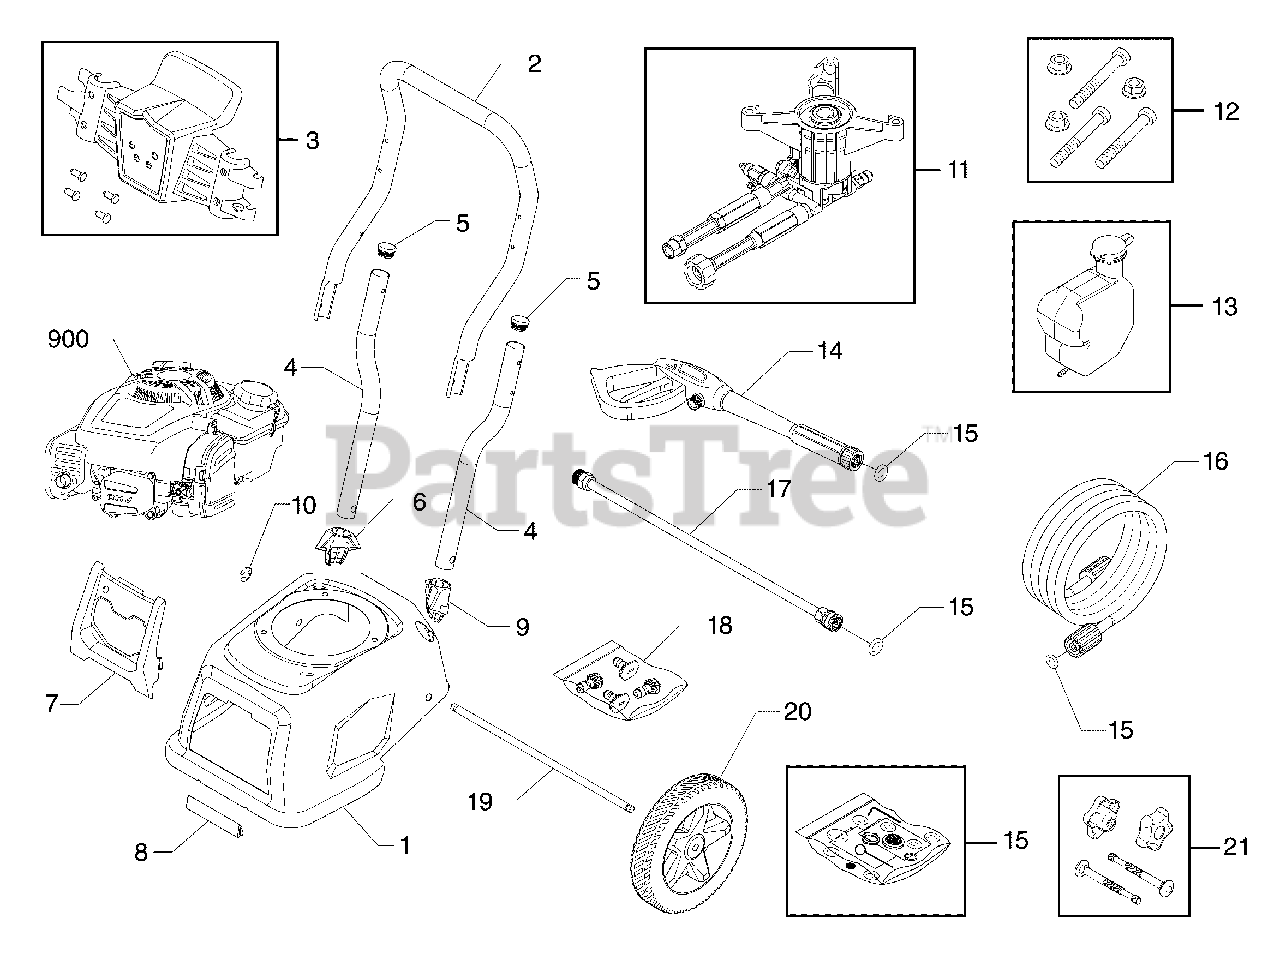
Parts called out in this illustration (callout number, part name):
8	MOUNT-VIBRATION
12	KIT, Hardware, Pump Mounting
13	TANK-CHEMICAL
14	GUN
15	KIT-O-RING MAINTENANCE
16	HOSE
17	EXTENSION, QC
18	Kit, Quick Connect Nozzles
21	KIT, Hardware, Handle
